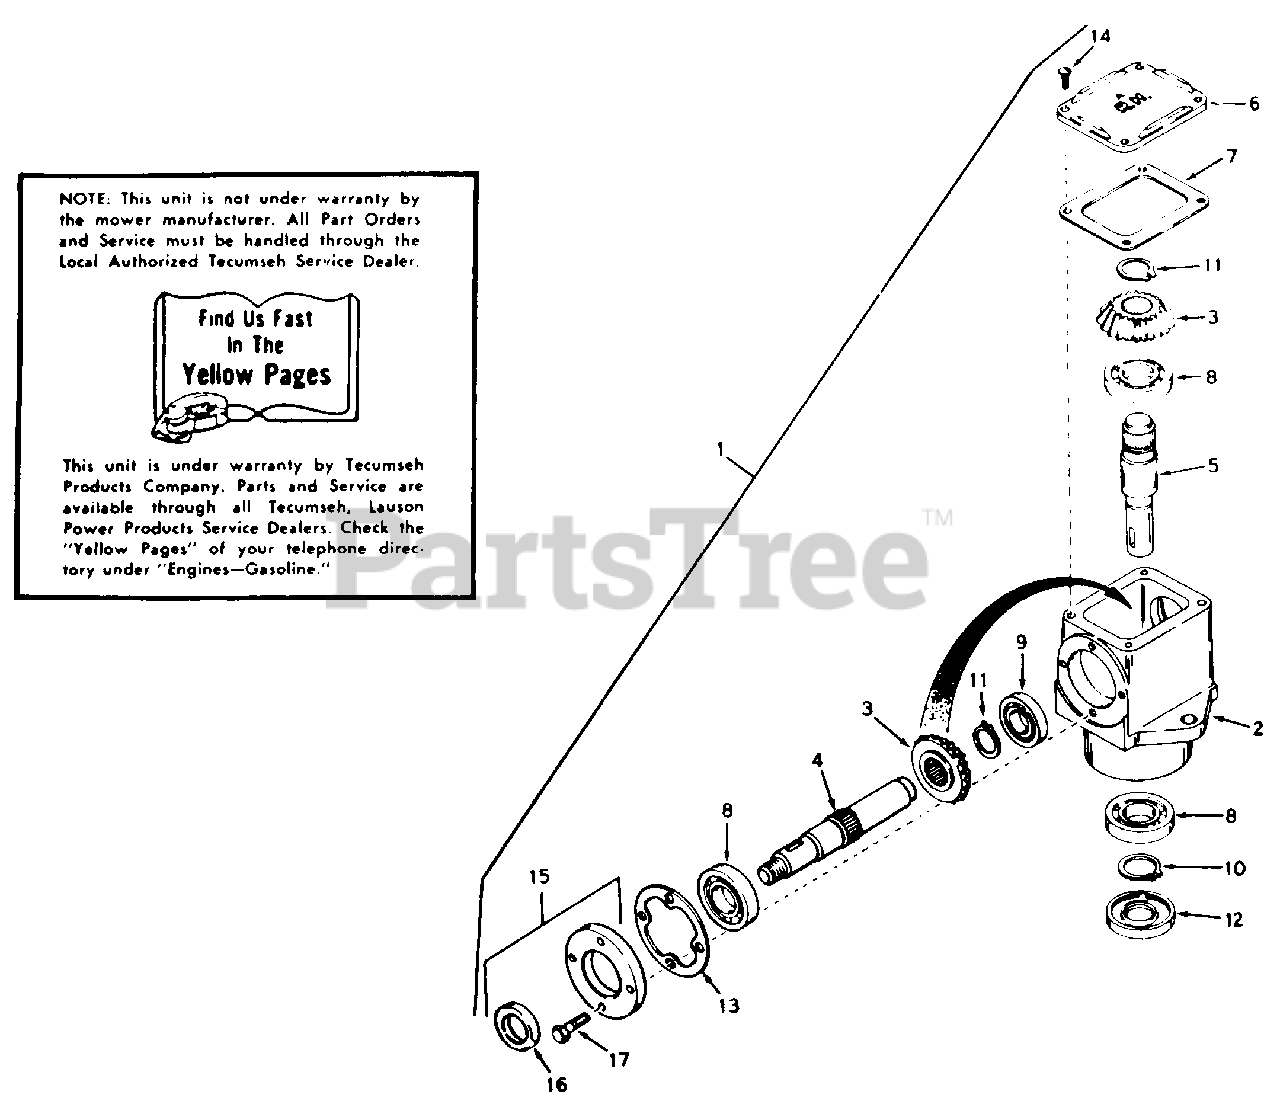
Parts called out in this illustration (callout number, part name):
1	Head Ass'y. R.H.
2	Housing, Right Angle Drive
3	Gear, Miter
4	Shaft, Input
5	Shaft, Output
6	Cover, Right Hand
7	Gasket, Cover
8	Bearing, Ball
9	Bearing, Ball
10	Ring, Snap
11	Ring, Snap
12	Seal, Oil
13	Gasket, Cap
14	Screw, Rd. Hd. Self Tap., 10-24 x 1/2
15	Cap & Seal Ass'y., Retainer
16	Seal, Oil
17	Screw, Hex Hd. 1/4-20 x 7/8
